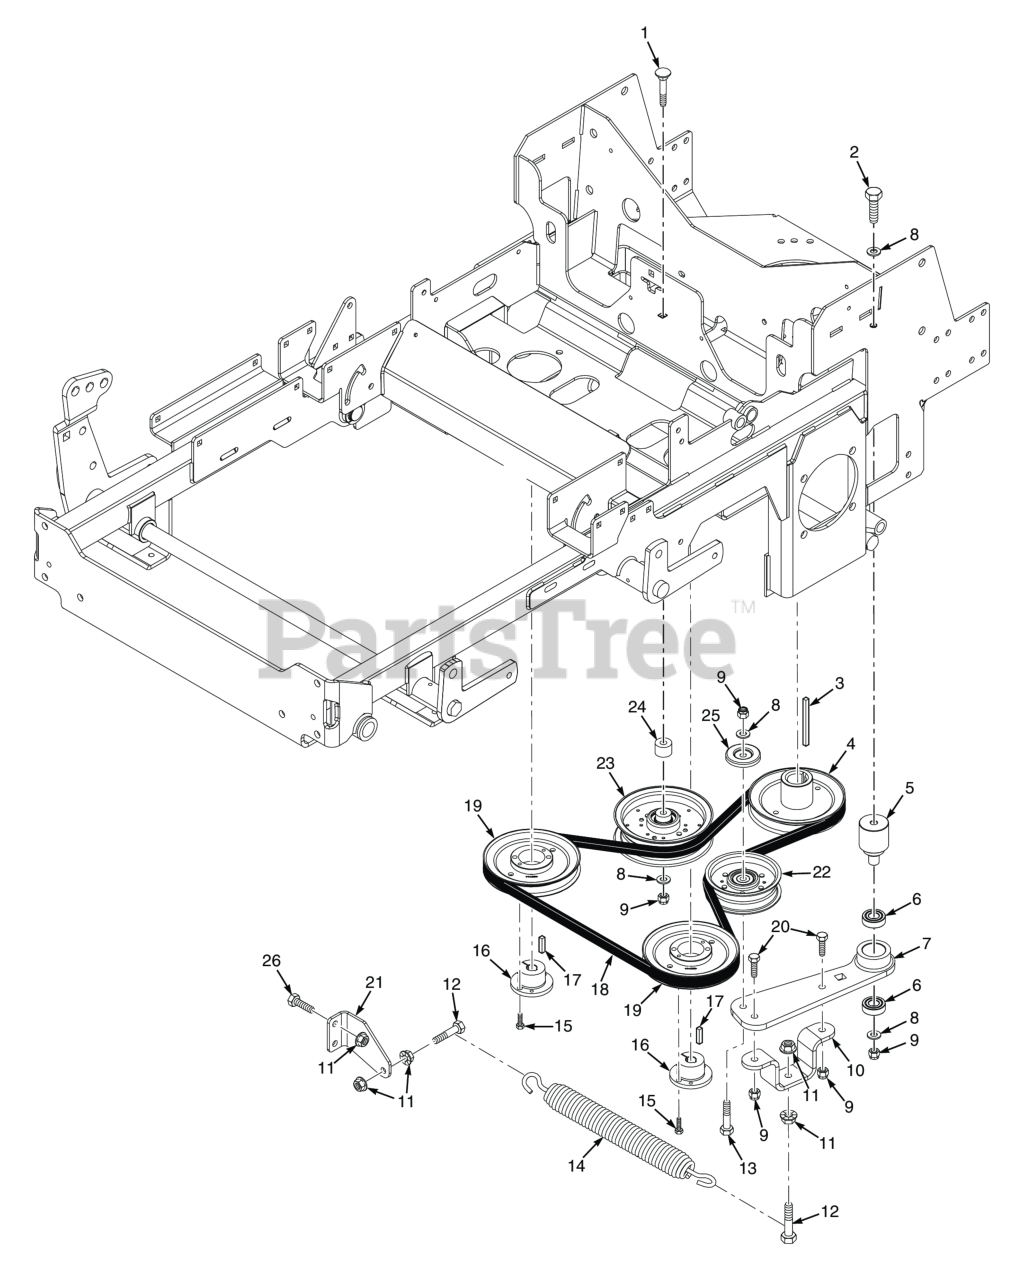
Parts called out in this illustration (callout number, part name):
1	Bolt, Carriage 3/8-16 x 3-1/4"
2	Bolt, Hex Head 3/8-16 x 4-1/4"
3	Key, 1/4 x 1/4 x 3-1/2"
4	Pulley, 5.75" Dia. - 1.125 Bore
5	Pivot, Idler Arm
6	BEARINGS, BALL, NEUTRAL RETURN
7	Idler Arm Assembly
8	Flatwasher, 3/8 (.391 x .938 x .105 HD) Grade 8
9	HEX NUT, ELASTIC STOP LOCK, 3/8-16
10	Mounting Bracket, Idler
11	NUT, 3/8-16 SERRATED FLANGE HEX HEAD
12	Bolt, Hex Head 3/8-16 x 1-1/2" Grade 8 Black
13	Bolt, Hex Head 3/8-16 x 2-1/4" - 61"
14	Spring, Pump Drive
15	Bolt, Hex Head 1/4-20 x 1" Grade 8 Black
16	Hub, Tapered, 15mm Bore
17	KEY, 5 MM X 5 MM X 25 MM
18	Belt, Pump Drive (61")
19	Pulley, 5.75 O.D. (Gasoline Engines)
20	Bolt, Hex Head 3/8-16 x 1-1/4", Kawasaki FX / FS
21	Bracket, Spring Anchor
22	Pulley, 4" Dia. Idler
23	Idler Pulley, Belt Clutch
24	Spacer, Idler
25	Quick Pin, 5/16" Dia.
26	Carriage Bolt, 3/8-16 x 1.0"
